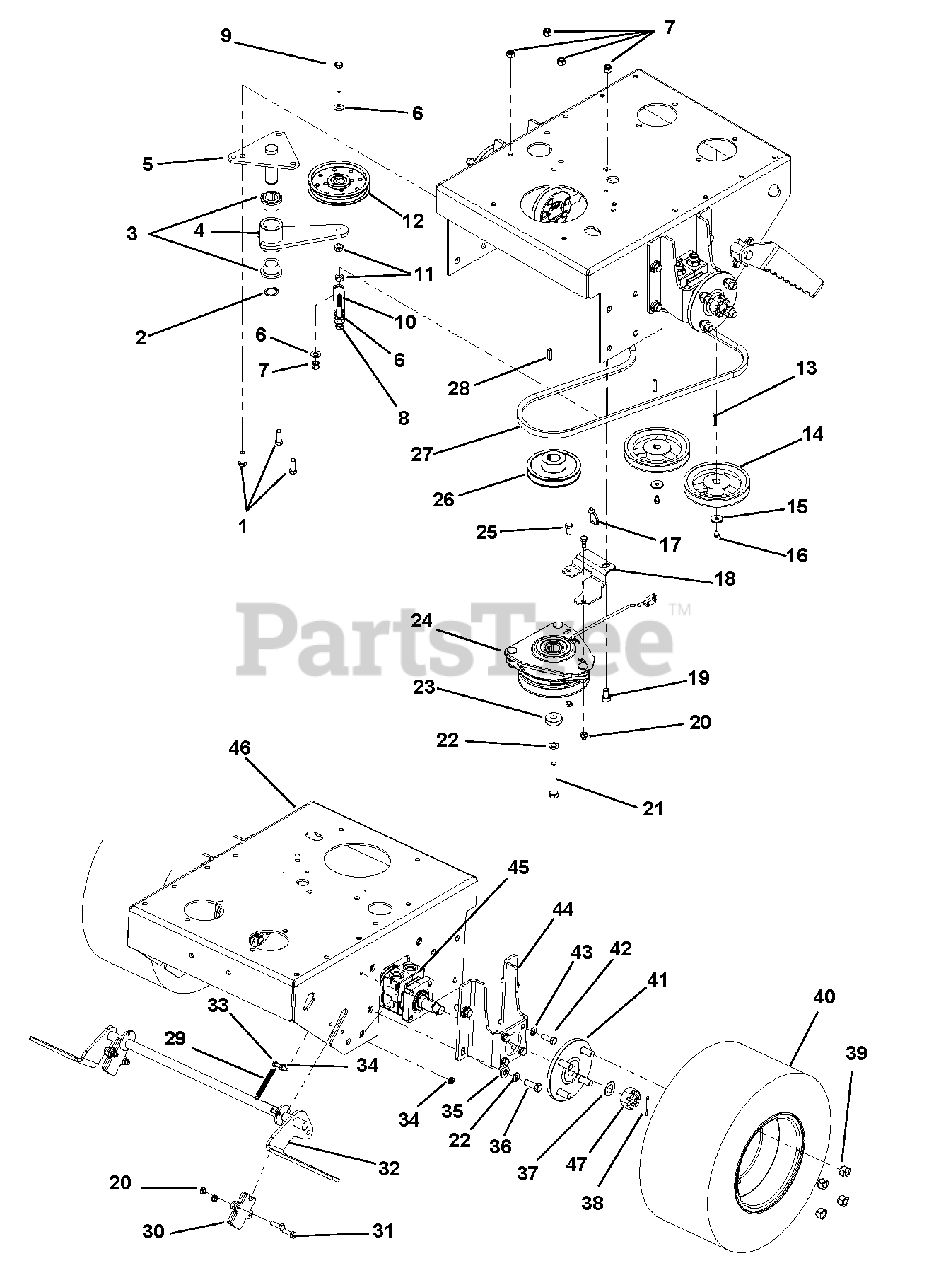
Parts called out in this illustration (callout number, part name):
1	BOLT, HEX .38-16 X 1.00 GR5 Y
2	SNAP RING, 1.00 X .042 EXT
3	BRG, FLG 1.00 X 1.25 X 1.00
4	WLDT, IDLER ARM
5	WLDT, IDLER PIVOT MOUNT
6	WASHER, .406 X .813 X .065 FLAT Y
7	LOCKNUT, 3/8-16 NYLOC Y
8	BOLT, 3/8-16 X 3.00 HEX 8 Y
9	BOLT, HEX .38-16 X 2.50 GR5 Y
10	SPRING, EXT .900X.135X4.50 Y
11	LOCKNUT, 3/8-16 WHIZ Y
12	PULLEY, FLAT 4.50 X .375 W/BRG
13	KEY, M5 X M5 X M30 RD
14	ASSY, PUMP PULLEY W/SET SCREW
15	WASHER, .250 WIDE HEAVY FLAT Y
16	BOLT, M6X1.00X10 HEX 8.8 Y
17	CABLE TIE, .15 X 8.50
18	PLATE, CLUTCH DOG
19	BOLT, 7/16-14 X .750 HEX 5 Y
20	LOCKNUT, 5/16-18 NYLOC Y
21	BOLT, HEX .44-20 X 3.00 G5 Y
22	WASHER, .438 MED SPRG LOCK Y
23	SPACER, .468 X 1.38 X .375 Y
24	CLUTCH ASSY, OGURA
25	BOLT, HEX .31-18 X .75 GR5 Y
26	PULLEY, V-BELT 4.45X1.00 W/KEY
27	BELT, HA 55.1 EL AMD OHR
28	KEY, .250 X .250 X .995 TPR
29	SPRING, EXT .375 X .055 X 2.25 Y
30	SHOE, BRAKE SYSTEM FLOAT WALK
31	BOLT, HEX .31-18 X 1.00 GR5 Y
32	WLDT, BRAKE SYS 36" FLWLK
33	BOLT, HEX .25-20 X 1.25 GR5 Y
34	LOCKNUT, 1/4-20 WHIZ Y
35	WASHER, .468X1.00X.125 FLAT Y
36	BOLT, HEX .44-14 X 1.25 GR5 Y
37	BUSHING, MACH .750 X 1.25 X .048 Y
38	PIN, COT .125 X 1.50 EXTP Y
39	NUT, 1/2-20 LUG C
40	ASSY, WHEEL & TIRE - 16X6.5-8
41	ASSY, WHEEL HUB
42	BOLT, 3/8-16 X 1 GR8 BLACK
43	WASHER, .375 MED SPRG LOCK Y
44	BRKT, MOTOR MOUNT FLWLK
45	MOTOR, HYDRAULIC WHEEL
46	WLDT, 18" ENG BED FXFL
47	NUT, .75 UNF2B HEX SLOT JDS14
